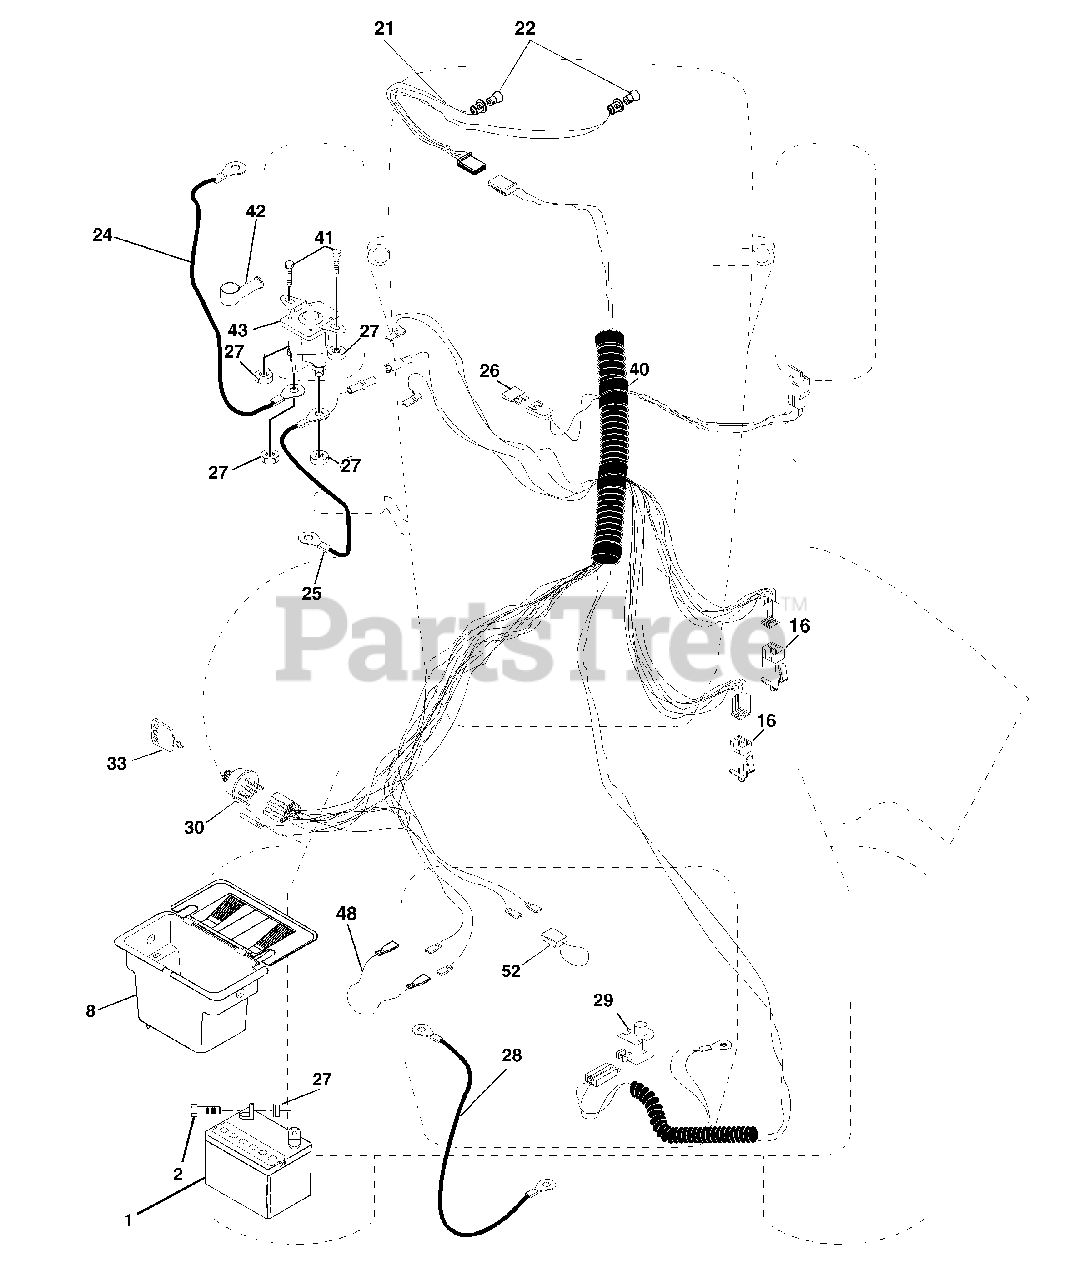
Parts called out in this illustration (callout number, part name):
1	Battery 12 Volt 25 Amp
2	Bolt Hex Hd 1/4-20unc X 3/4
8	Case Battery Mech Hiinge
16	Switch Interlock Push-In
21	Harness Asm Light W/4152j
22	Bulb Light #1156
24	Cable Battery 6 Ga 11"red
25	Cable Battery
26	Fuse 20 AMP
27	Nut Keps Hex 1/4-20 Unc
28	Cable Ground 6 Ga 12"black
29	Switch Plunger Nc Gray
30	Switch Ign
33	Key Ign
40	Harness Ign
41	Bolt Blk Fin Hex 1/4-20
42	Cover Terminal Red
48	Adapter Ammeter
52	Protection Wire Loop
